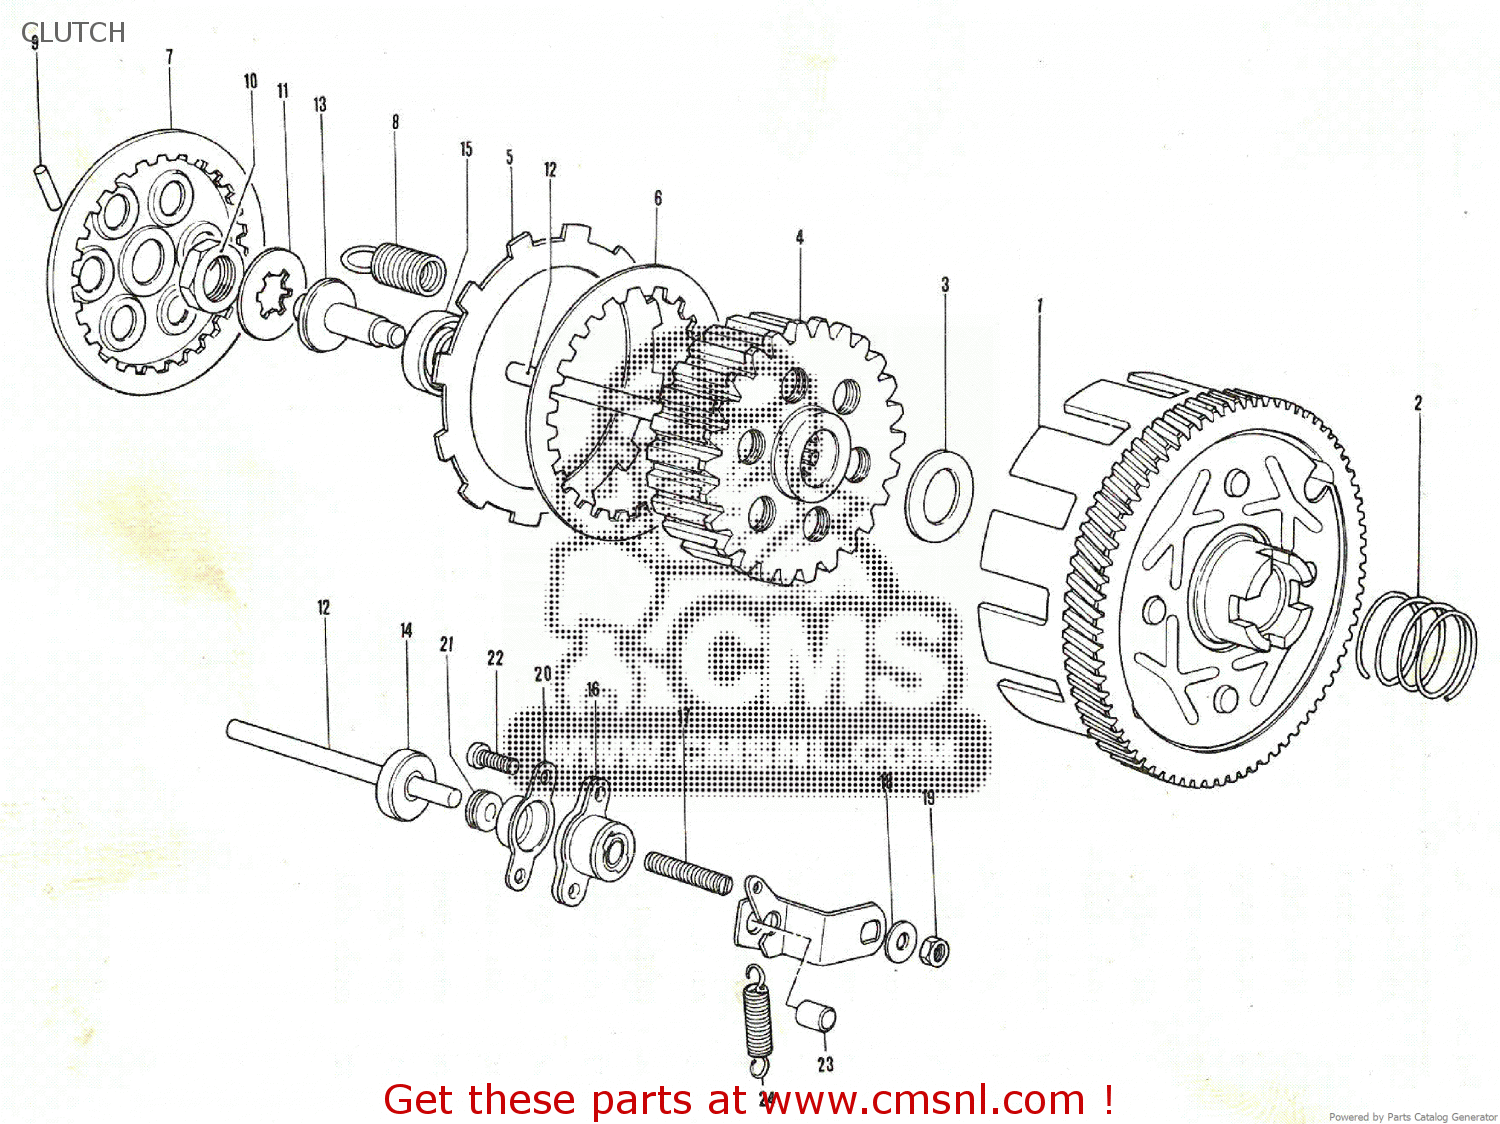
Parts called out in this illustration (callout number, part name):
1	GEAR ASSEMBLY,PRIMARY DRIVE
2	SPRING
3	WASHER
4	HUB,CLUTCH SLEEVE
5	PLATE,CLUTCH DRIVE (MCA)
6	PLATE,CLUTCH DRIVEN (NAS)
7	PLATE,CLUTCH PRESSURE
8	SPRING
9	PIN(2.5X19.8)
10	NUT
11	WASHER,LOCK
12	PUSH ROD
13	ROD,CLUTCH RELEASE
14	SEAL,OIL(5.5X16X8)
15	SEAL,OIL (10X17X5)
16	SCREW ASSEMBLY,CLUTCH RELEASE
17	SCREW
18	WASHER(6.5X16X1.2)
19	NUT
20	COVER,CLUTCH RELEASE SCREW
21	SEAL,DUST(5.3X13X5)
22	SCREW
23	PIECE,RELEASE ARM END
24	SPRING
